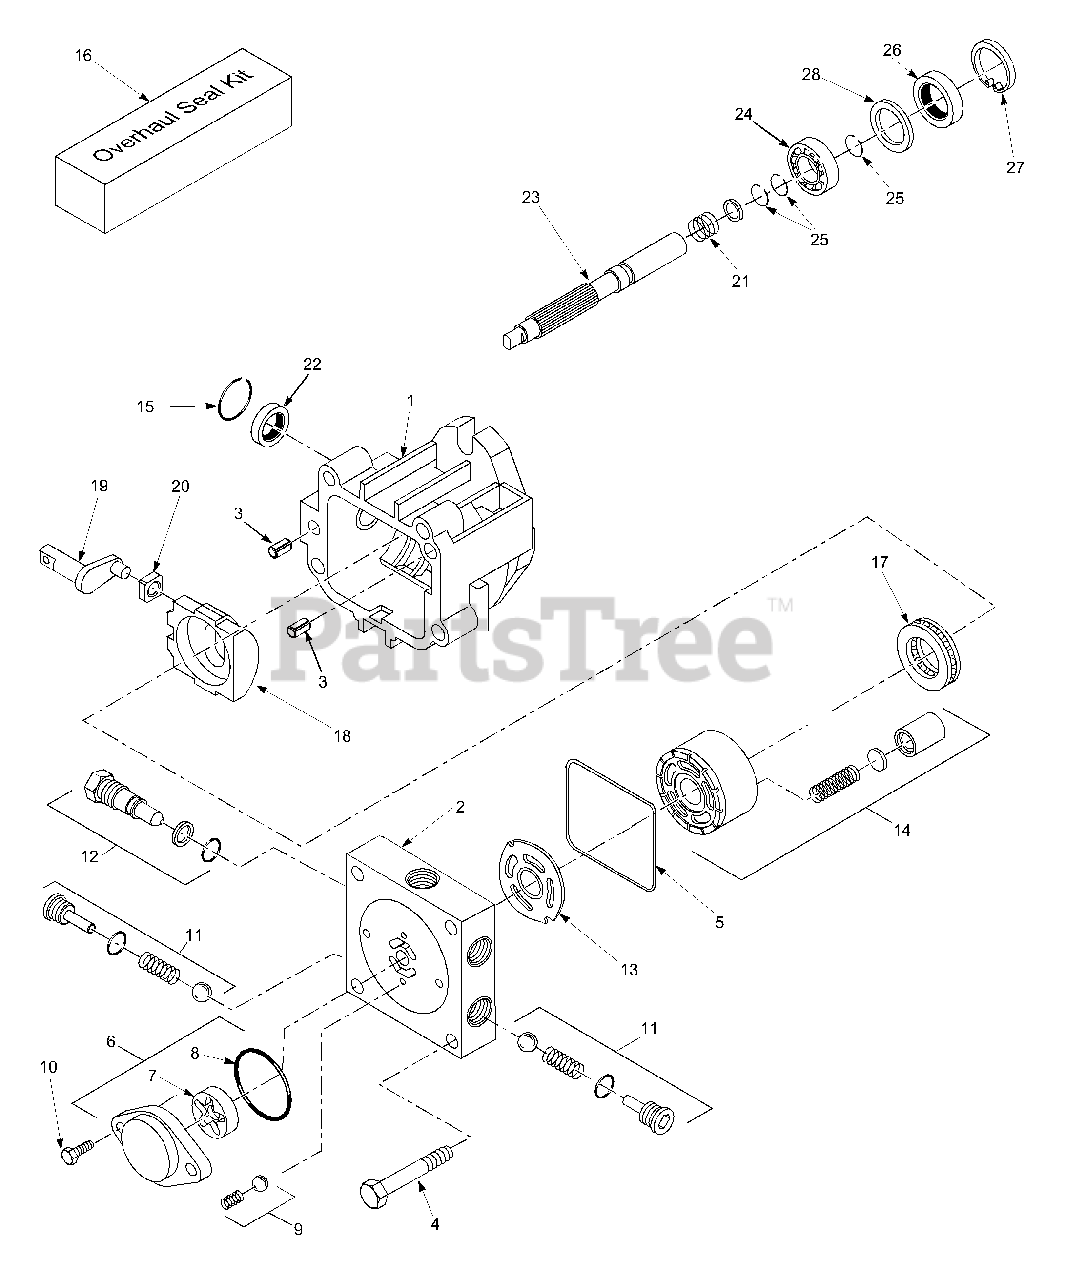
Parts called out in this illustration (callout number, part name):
1	Housing Kit
2	End Cap
3	Straight Headless Pin
4	Socket Head Screw
5	End Cap Gasket
6	Charge Pump Kit
7	Gerotor Assembly
9	Charge Relief Valve Kit
10	Socket Head Screw
11	Check Valve Kit
12	Bypass Valve Kit
13	Valve Plate
14	Cylinder Block Kit
15	Trunion Seal Retaining Ring
16	Overhaul Kit
17	Roller Thrust Bearing
18	Swash Plate
19	Trunnion Arm
20	Guide Slot
21	Block Spring
22	Lip Seal
23	Pump Shaft
24	Ball Bearing
25	Retaining Ring
26	Lip Seal
27	Retaining Ring
